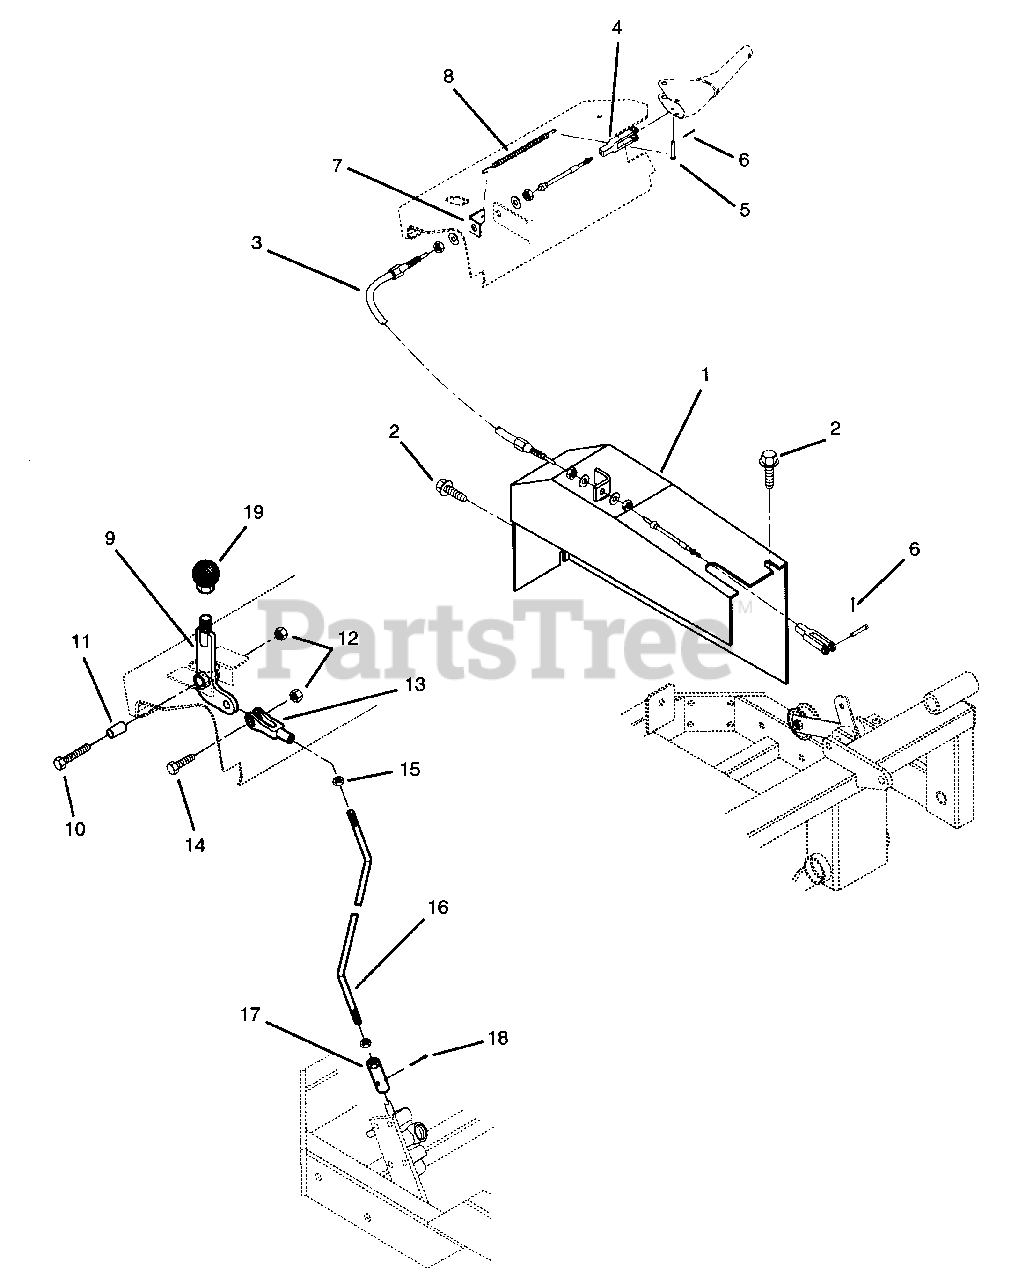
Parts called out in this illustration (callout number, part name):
1	Shield Weldment(Belt)
2	Screw-Hex Head Whizlock .312 x 1
3	Control Cable
4	Clevis .188 Rod x .25 Hole
5	Pin-Clevis .25 x 1.25 Plated
6	Pin-Cotter .12 x 1.0 Plated
7	Spring Tab
8	Spring-Tension .50 OD x 3.5 LG
9	Valve Lever Weldment
10	Bolt-Hex .38-16 x 1.50 Plated Grade 5
11	Bushing-Sleeve P/M Bronze .5 OD x .38 IDx 1 LG
12	Nut-Lock Unitorque .38
13	Yoke End .375-24 x 2.25 LG Plain
14	Bolt-Hex .38-16 x 1.25 Plated Grade 5
15	Nut-Jam .375-24 Plated
16	Valve Lever Rod
18	Pin-Cotter .18 x 1.0 Plated
19	Knob-Black Ball
